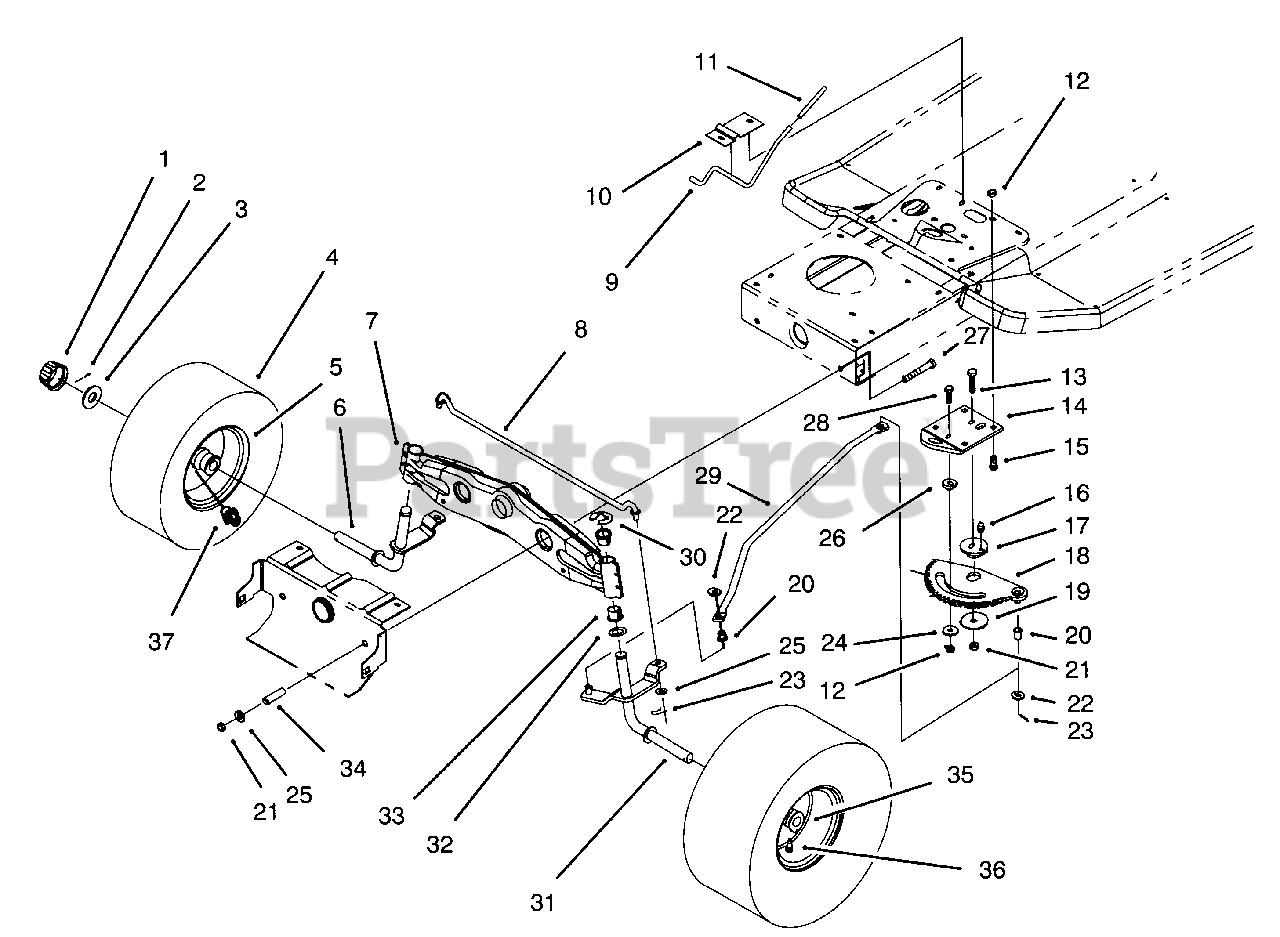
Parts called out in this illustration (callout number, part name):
2	Pin-Cotter
4	Tire-13" (Model No. 81140 Only)
5	Rim-Front Wheel (Model No. 81140 Only
5	Rim-Front Wheel (Model No. 81180 & 81181 Only)
6	Spindle-R.H.
7	Axle-Front
8	Rod-Steering Tie
9	Rod-Parking Brake
10	Bracket-Parking Brake
11	Grip-Brake Rod
12	Nut-Lock
13	Screw-Carriage
14	Bracket-Steering Rack
15	Bolt-Carriage
16	Fitting-Grease
17	Bushing-Eccentric
18	Rack-Steering
19	Washer-Fender
20	Bushing-Steering Link
21	Nut-Lock
22	Washer-Flat
23	Pin-Cotter
24	Washer-Fender
25	Washer-Flat
26	Spacer-Steering Rack
27	Screw-Hex Hd. Cap
28	Screw-Carriage
29	Link-Drag
31	Spindle-L.H.
32	Washer-Thrust
33	Bushing-Steering Spindle
34	Spacer-Front Axle
35	Bearing-Wheel
36	Valve Stem w/Cap
37	Fitting-Grease
